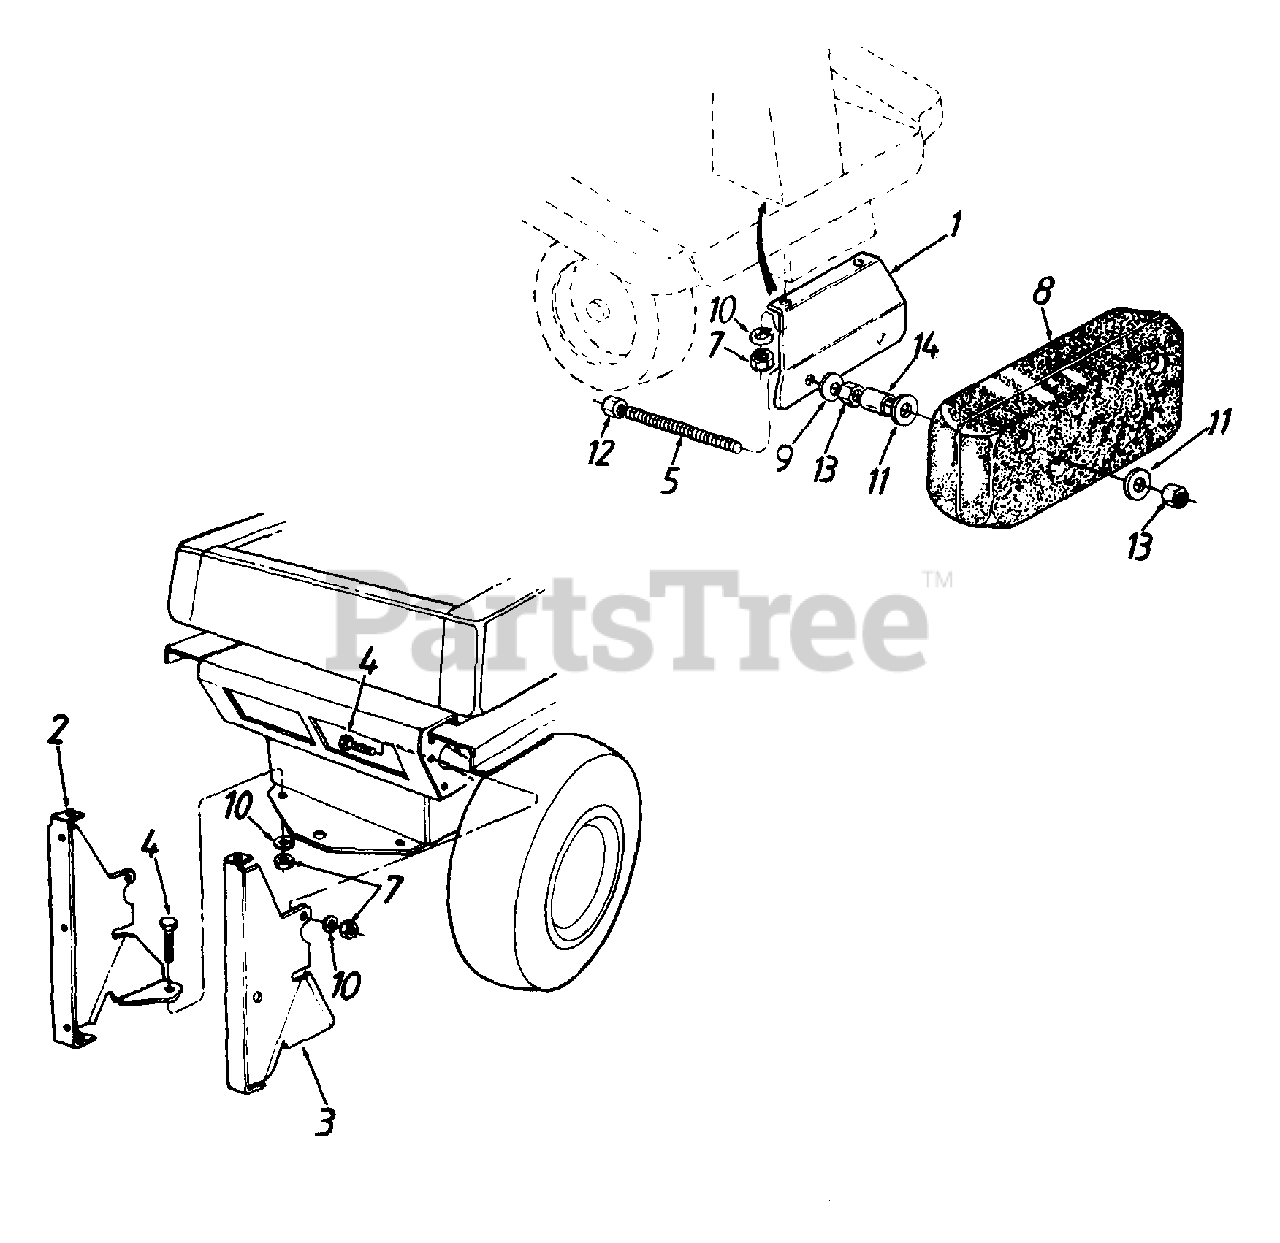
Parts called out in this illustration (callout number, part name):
3	Catcher Support Brkt. - L.H.
4	Hex Bolt 5/16-18 x 1.0" Lg.
5	Stud 7/16-14 x 5-5/8" Lg.
7	Hex Nut 5/16-18 Thd.
8	Front Counterweight
9	Bell-Wash. 7/16" I.D.
10	L-Wash. 5/16" I.D.
11	Fl-Wash. .45" I.D.
12	Hex L-Nut 7/16-14 Thd.
13	Hex Nut 7/16-14 Thd.
14	Spacer
